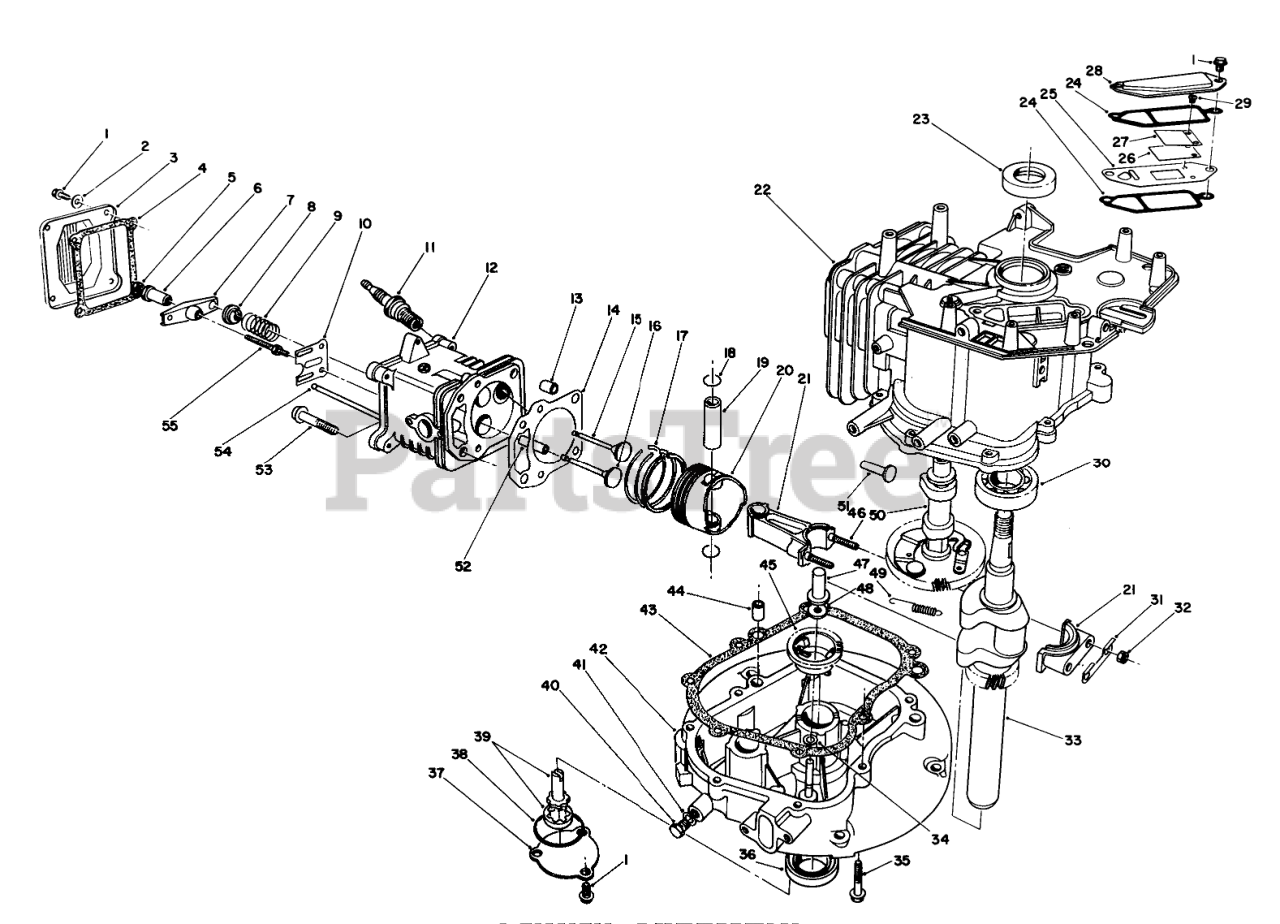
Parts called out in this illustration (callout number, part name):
2	WASHER
3	COVER
4	GASKET
6	PIVOT
8	RETAINER
9	SPRING
10	GUIDE
11	SPARK PLUG
12	Head-Cylinder (Incl. Ref. #52)
14	GASKET
15	VALVE-INTAKE
16	VALVE-EXHAUST
17	RING SET
18	CIRCLIP
20	PISTON
21	Connection Rod Assembly (Incl. Ref. #31, 32 & 46)
22	Block-Engine (Incl. Ref. #23, & 30)
24	GASKET
25	Plate-Breather
26	Valve-Reed
27	Retainer-Reed Valve
28	COVER
29	Screw-Reed Valve
30	BEARING
31	Plate-Lock
33	CRANKSHAFT
34	WASHER
37	COVER
38	O-RING
39	OIL PUMP
40	OIL DRAIN PLUG
41	GASKET
42	Crankcase
43	GASKET
45	GOVERNOR FLYWEIGHT ASM
47	PLUNGER
48	WASHER
49	SPRING
50	Camshaft Assy. (Incl. Ref. #49)
51	TAPPET
52	GUIDE
